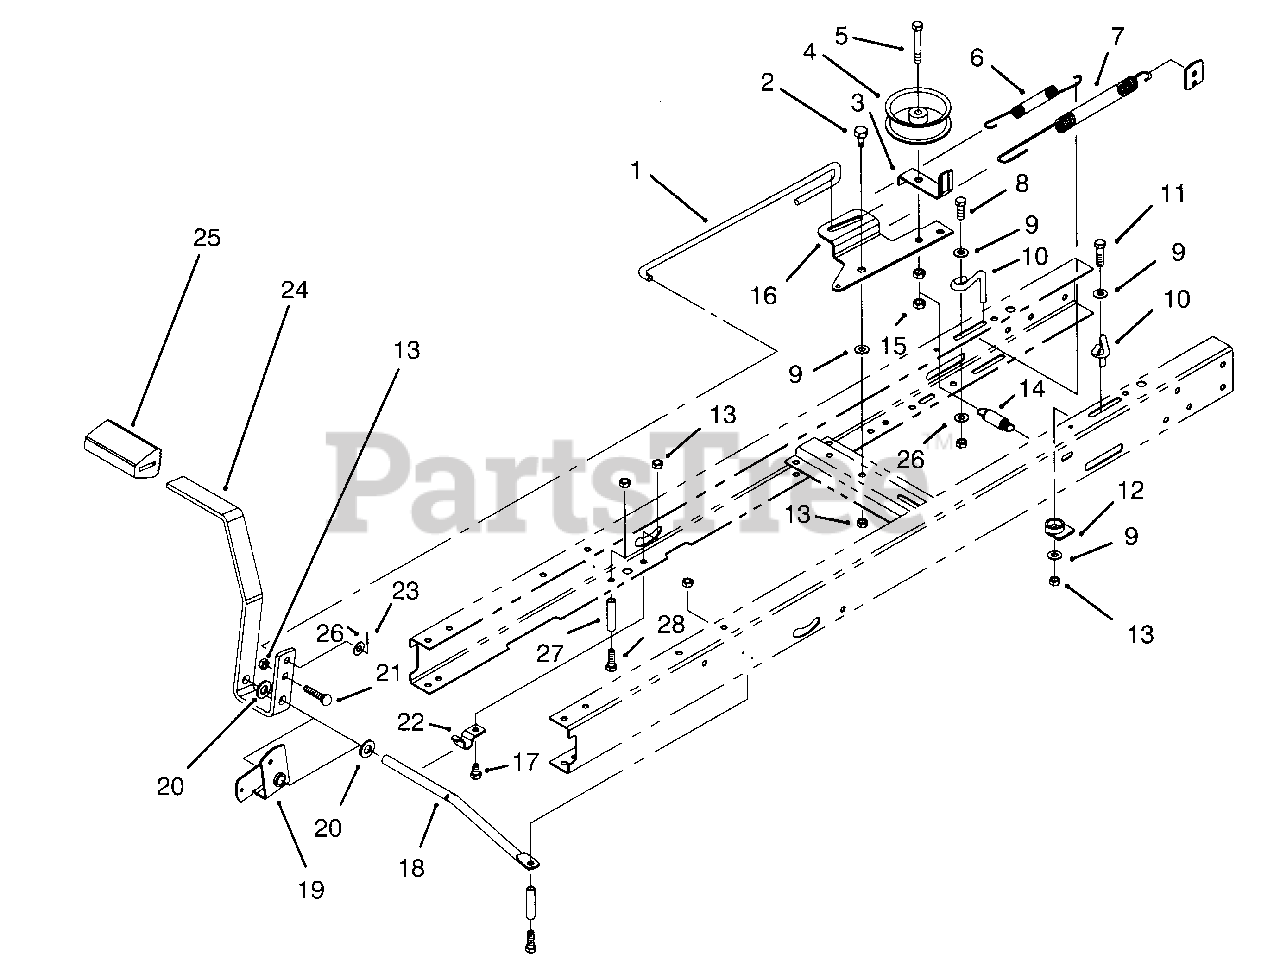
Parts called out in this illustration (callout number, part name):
1	Rod-Clutch/Brake
2	Bolt-Shoulder
3	Guide-Idler Belt
4	Pulley-Flat Idler
5	Screw-Hex Hd. Cap
6	Spring-Pedal Return
7	Spring-Brake
8	Screw-Hex Hd. Cap
9	Washer-Flat
10	Guide-Trans. Belt
11	Screw-Hex Hd. Cap
12	Guide-Cable
13	Nut-Lock
14	Spring-Extension
15	Nut-Lock
16	Arm-Idler
17	Screw-Hex Hd. Cap
18	Rod-Pedal Pivot
19	Bellcrank
20	Washer-Flat
21	Bolt-Carriage
22	Clamp-Shift Pivot
23	Pin-Cotter
24	Pedal-Clutch/Brake
25	Pad-Pedal
26	Washer-Flat
27	Spacer-Tube
28	Screw-Hex Hd. Cab
